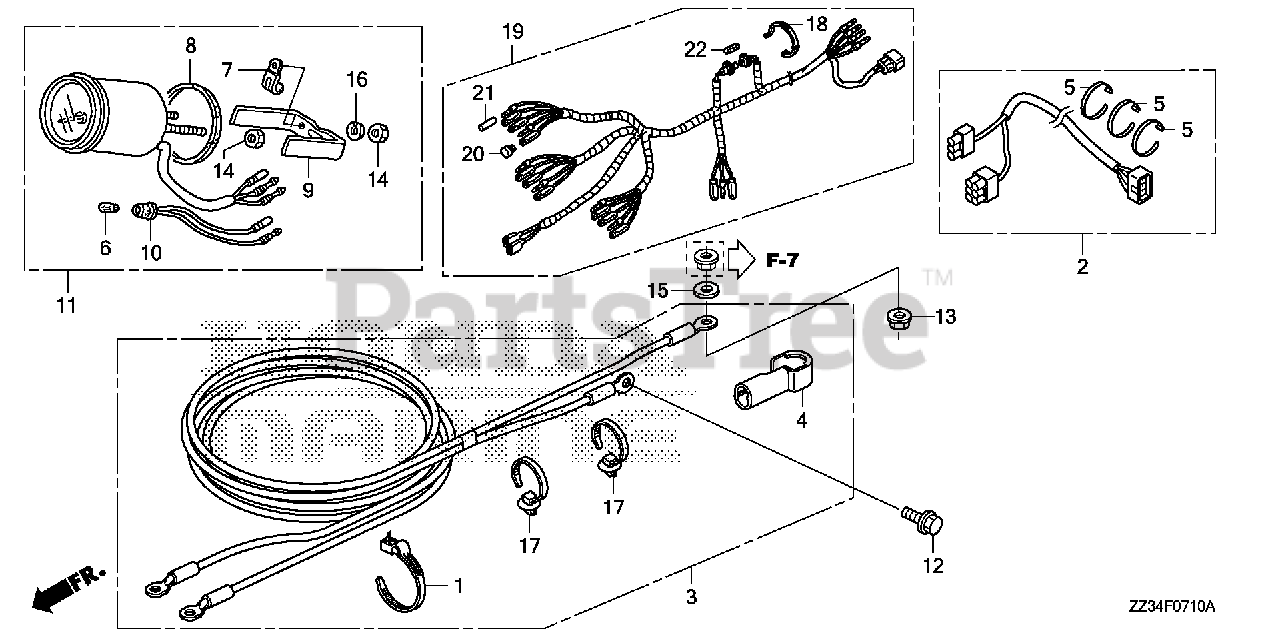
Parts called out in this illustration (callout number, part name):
1	BAND, WIRE
3	CABLE ASSY., STARTER
4	COVER, STARTER TERMINAL
12	BOLT, FLANGE (8X18)
13	NUT-WASHER (8MM)
15	WASHER, PLAIN (8MM)
17	CLIP, HARNESS BAND (145MM) (BLACK)
